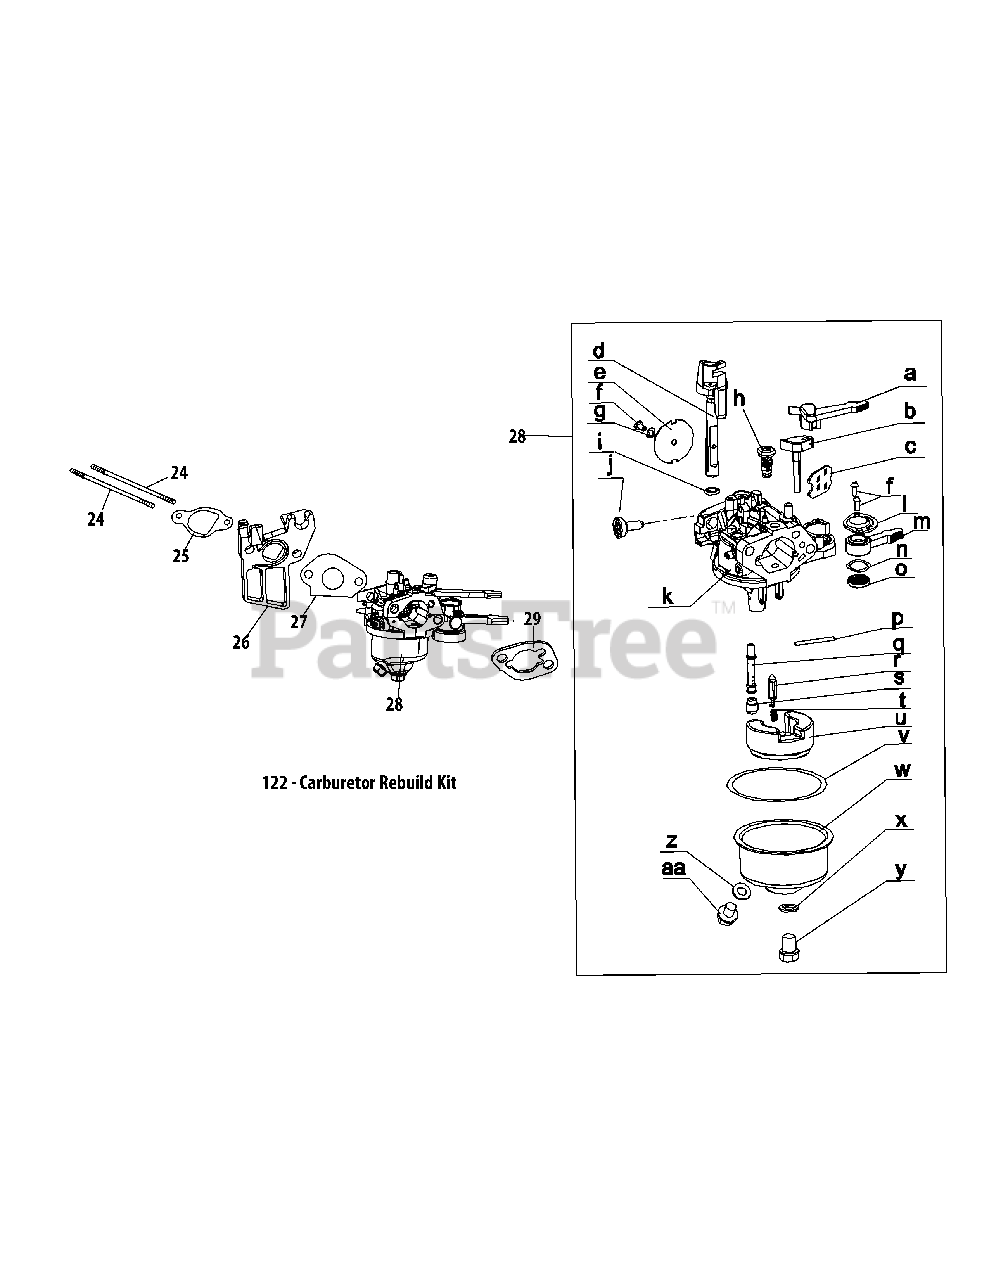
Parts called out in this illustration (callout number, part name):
24	Carburetor Stud Bolt
25	Carburetor Insulator Gasket
26	Carburetor Insulator
27	Carburetor Gasket
28	Carburetor Assembly
29	Carburetor Gasket Plate
122	Carburetor Rebuild Kit
